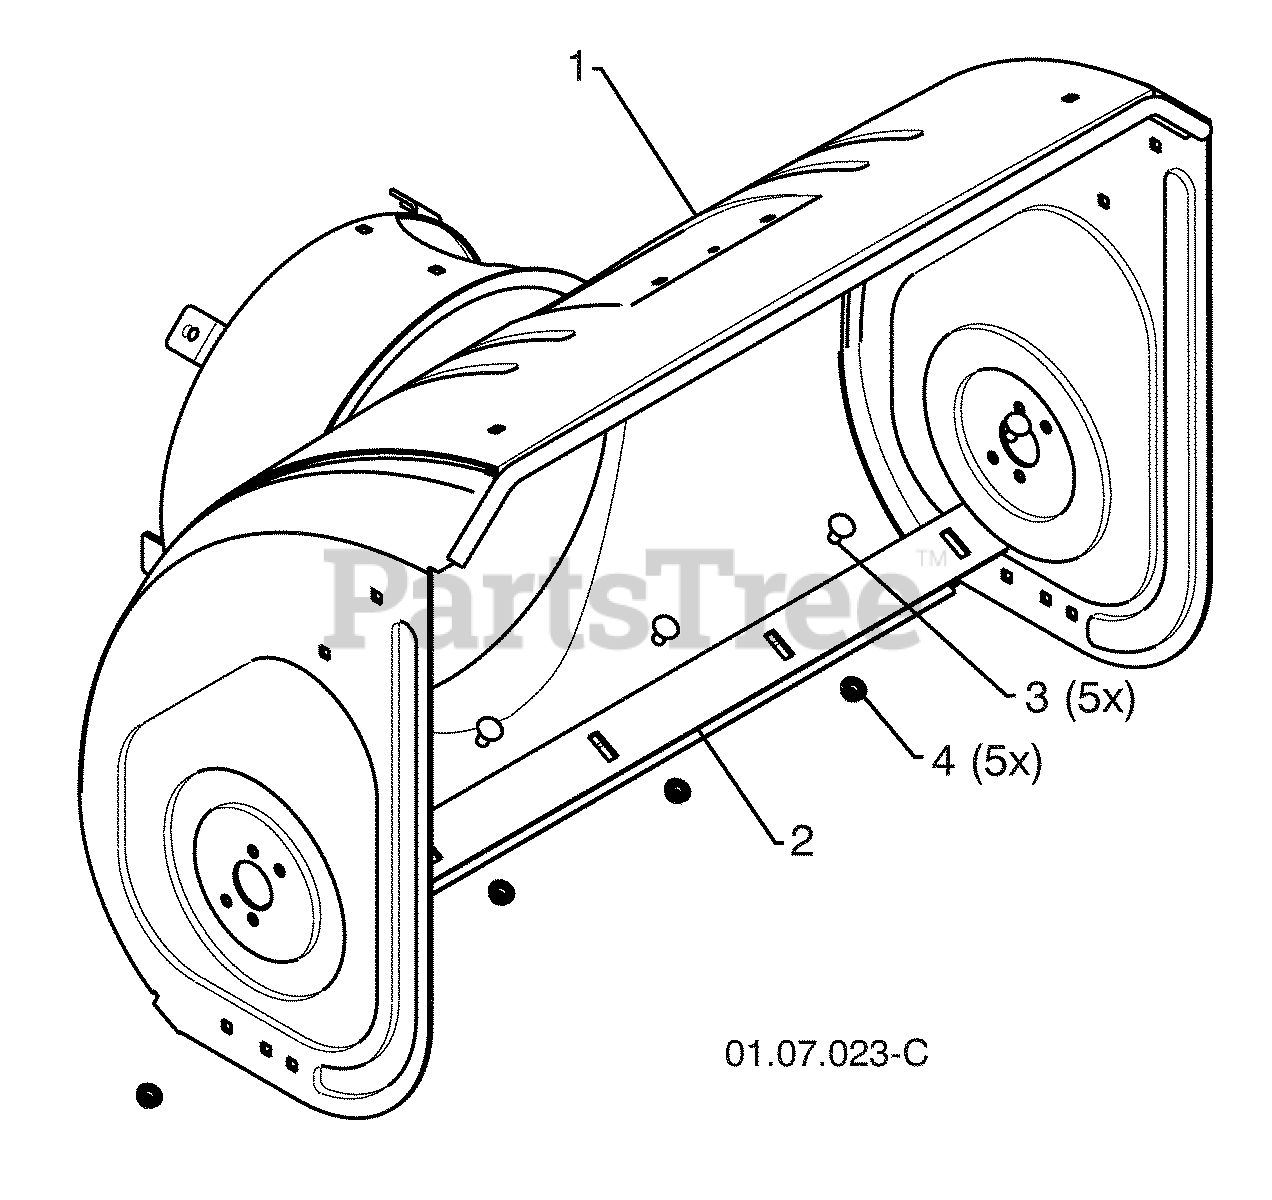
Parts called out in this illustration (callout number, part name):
1	AUGER HOUSING
2	SCRAPER BAR
3	CARRIAGE BOLT 5/16-18 X .625
4	NUT 5/16-18
